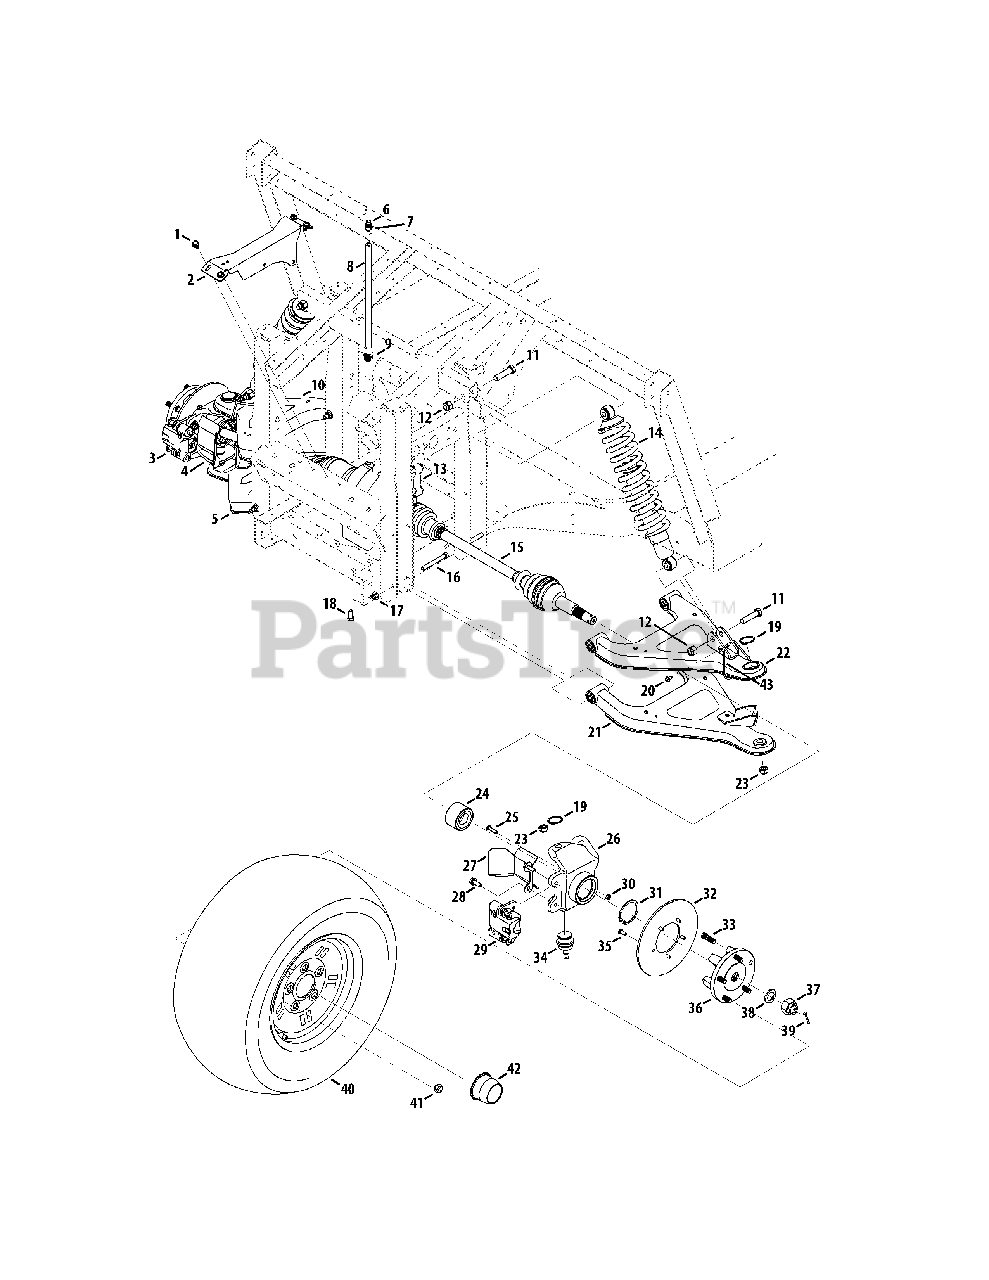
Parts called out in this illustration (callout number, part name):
1	Screw, tt, 5/16-18 x 0.500
2	Front Mount, differential, 4x4
3	Brake, hydraulic, caliper, frt, RH
4	Housing, knuckle, r/frt, mach
5	Control Assembly, r/frt, lower
6	Vent,3/8 Dia
7	Clamp, hose, .490 Dia.
8	Hose, Fuel Line
9	Clamp, Hose, Adj.
10	Arm Assembly, r/frt, upper
11	Screw, 1/2-13 x 2.00, gr5, std
12	Nut, Hex Lock, 1/2-13, Nylon
13	Differential Assembly, cfd, 4x4
14	Shabs, 5.0 Stroke, front
15	Axle Assembly, cv Joint, 4x4
15	DOJ Boot Kit (Includes clamp)
15	Rzeppa Boot Kit (Incl. clamp)
16	Screw, 3/8-16 x 3.00, gr8, std
17	Nut, Flange Lock, 3/8-16, Nylon
18	Screw, 3/8-16, .75, gr5, std
19	Ring, retainer, 34 x 1.6
20	Screw, tt, 1/4-20 x .500
21	Control Assembly, l/ftr, lower
22	Control Assembly, l/frt, upper
23	Nut, Nylock, m12 x 1.25
24	Bearing, dble Row, 60x30x37
25	Screw, 1/4-20 x 1.00, gr5, spec
26	Housing, knuckle, l/frt, mach
27	Bracket, Steering Shield, LH
27	Bracket, Steering Shield, RH
28	Screw, m8-1.25, 25.00
29	Brake, hydraulic, caliper, frt, LH
30	Nut, Hex, 1/4-20, gr5
31	Ring, retainer, dho-60
32	Disc, brake, 8.00x.188
33	Stud, rib Neck, 7/16-14 x 1.6
34	Ball Joint, 14d-6201
35	Screw, 1/4-20 x .625, gr5, lock
36	Hub, wheel
37	Nut, slotted, 22x1.5
38	Washer, flat, .88 x 1.38 x .125, ht
39	Pin, cotter, 5/32, 1.25
40	Wheel Assembly, RH, 25 x 10-12
40	Wheel Assembly, RH,25x10-12, Black
40	Wheel Assembly, LH, 25 x 10-12
40	Wheel Assembly, LH,25x10-12, Black
40	Tire Only, 25 x 10-12
41	Nut, lug, 7/16-14
41	Nut, lug, 7/16-14, Chrome
42	Cap, Wheel
42	Cap, Wheel, Chrome
43	Wire, Brake Line
